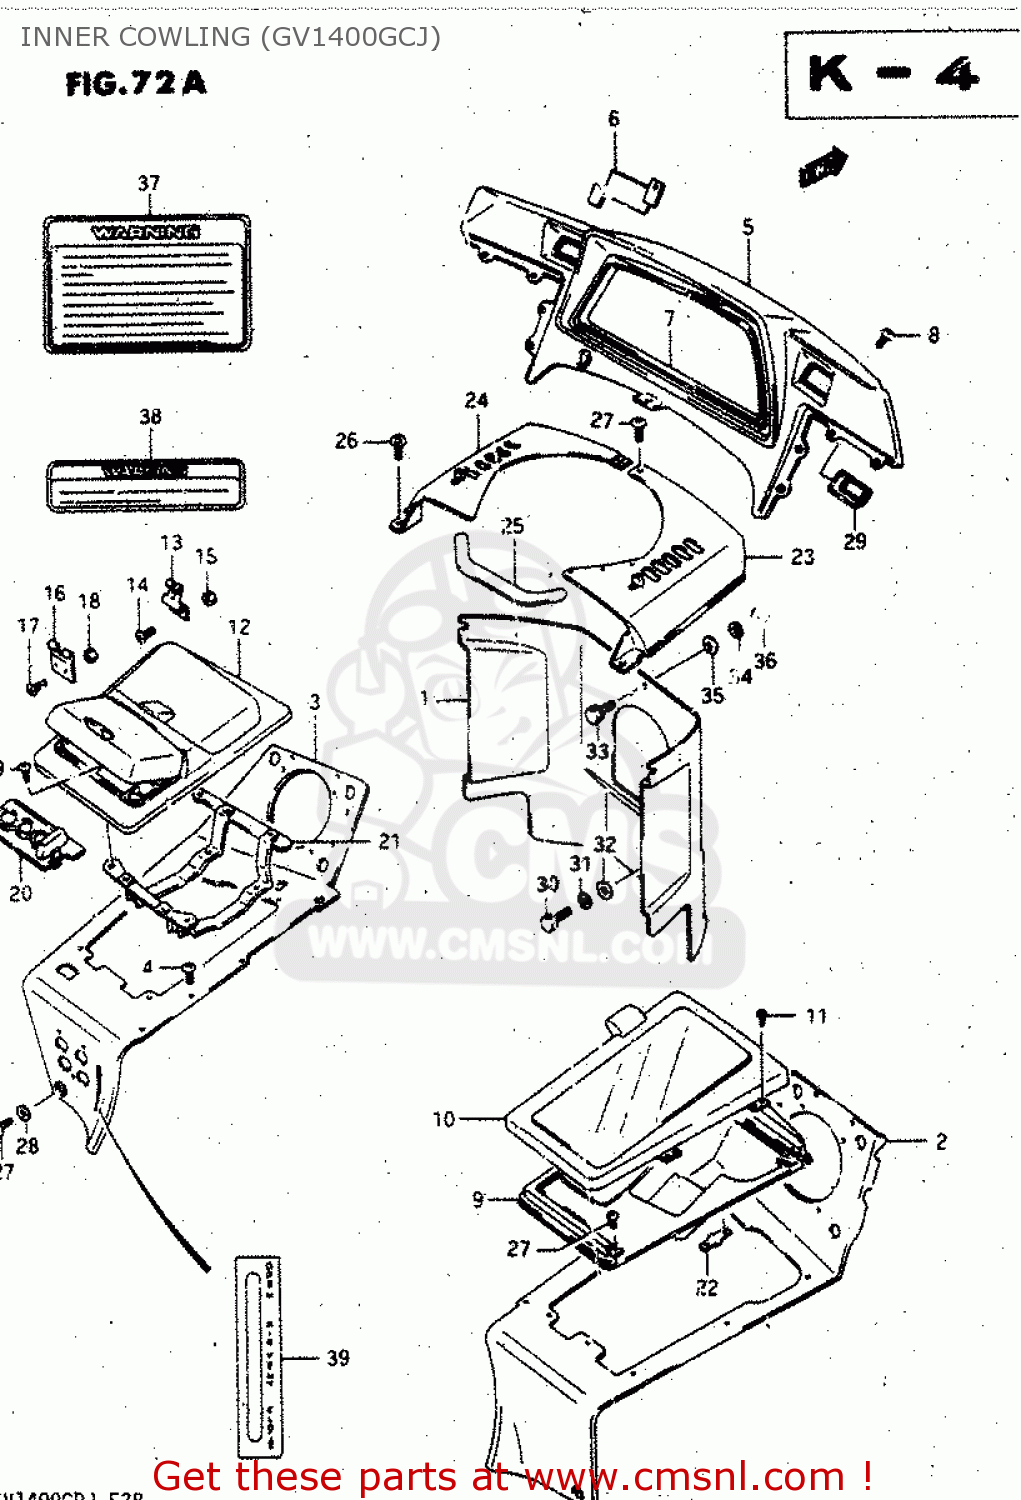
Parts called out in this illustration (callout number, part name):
1	COVER,COWLING,INNER
2	PANEL,COWLING,R
3	PANEL,COWLING LH
4	SCREW
5	COVER ASSY,METER
6	COVER,METER COVER HOLE
7	MOLDING,METER COVER
8	SCREW
9	BOX COMP,COWLING PANEL,RIGHT
10	CASE SET,COWL PANEL BOX MAP
11	SCREW
12	BOX COMP,COWLING PANEL,LEFT
13	HINGE
14	SCREW
15	NUT
16	HINGE,COWLING BOX LID NO
17	SCREW
18	NUT
19	SCREW 5X10
20	CASE,COIN HOLDER
21	BRACKET COMP,COWLING BOX
22	PLATE,PANEL BOX BASE
23	COVER ASSY,FRAME HEAD,R(BLACK)
24	COVER ASSY,FRAME HEAD,L(BLACK)
25	SEAL,FRAME HEAD
26	SCREW
27	SCREW
28	WASHER (4.3X13X0.80)
29	CAP,RADIO IND
30	BOLT
31	LOCK WASHER
32	WASHER,5.5X12X
33	BOLT
34	LOCK WASHER
35	WASHER,5.5X12X
36	NUT
37	LABEL (WARNING)
38	LABEL (WARNING COVER CO
39	EMBLEM,PANEL COWLING,LEFT
